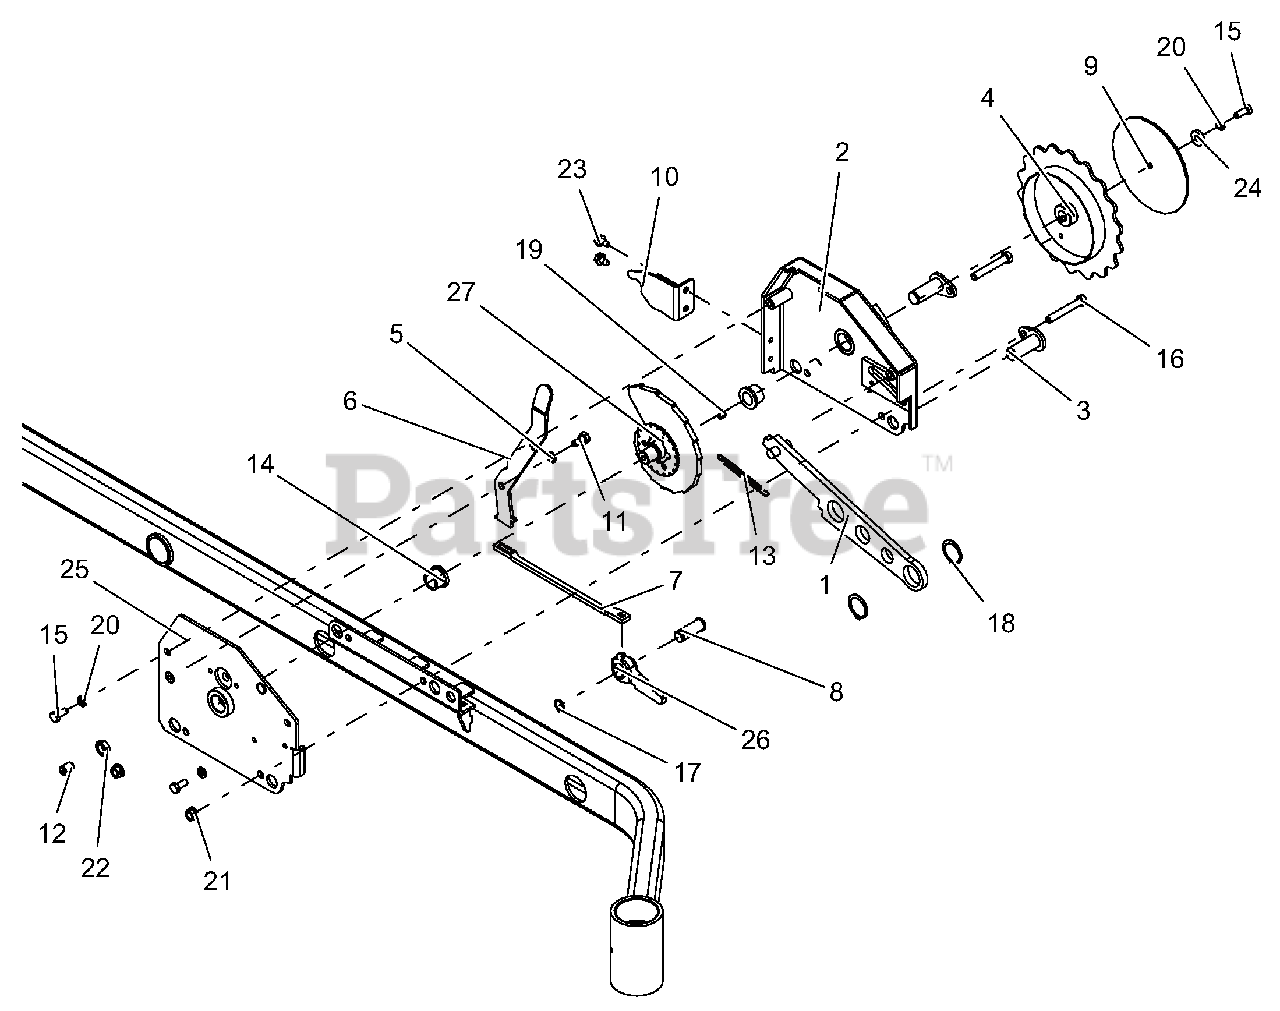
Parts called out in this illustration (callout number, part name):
1	WLDMT, HOC LINK-BLACK
2	WLDMT, HOC INNER-RED
3	WLDMT, PIN
4	WLDMT, DIAL, HOC
5	WAVE WASHER .390X.655X.110
6	LEVER, TRANSPORT LOCK-BLACK
7	LINK, TRANSPORT LOCK
8	PIN, CLEVIS .625 SNAP RING
9	PLATE, DIAL-RED
10	GUARD, DECK LIFT
11	BOLT, SHLDR .38-16 x .437 HEX YZ
12	BALL SPRING PLUNGER, .500-13
13	SPRG, EXTENSION
14	BUSHING, .750 X 1.00 X .750
15	BLT-HEX .31-18X.75 GR5 YWZC
16	BLT-HEX .38-16X2.50 GR5 YWZC
17	RG-RTNG-EXT .625x.050
18	RG-RTNG-EXT 1.25x.050
19	KEY-SQ .188X.188X.375
20	WSHR-LK .31X.078 REG YWZC
21	NUT, LK-CTR-FLG .38-16 YWZC
22	NUT, JAM .500-13 YWZC
23	SCR-TAP .31-18X.50 HWH TR YWZ
24	WSHR-FL-STL .328X.87X.179 YWZC
25	WLDMT, HOC OUTER-RED
26	WLDMT, LOCK PAWL
27	WLDMT, CAM HOC
